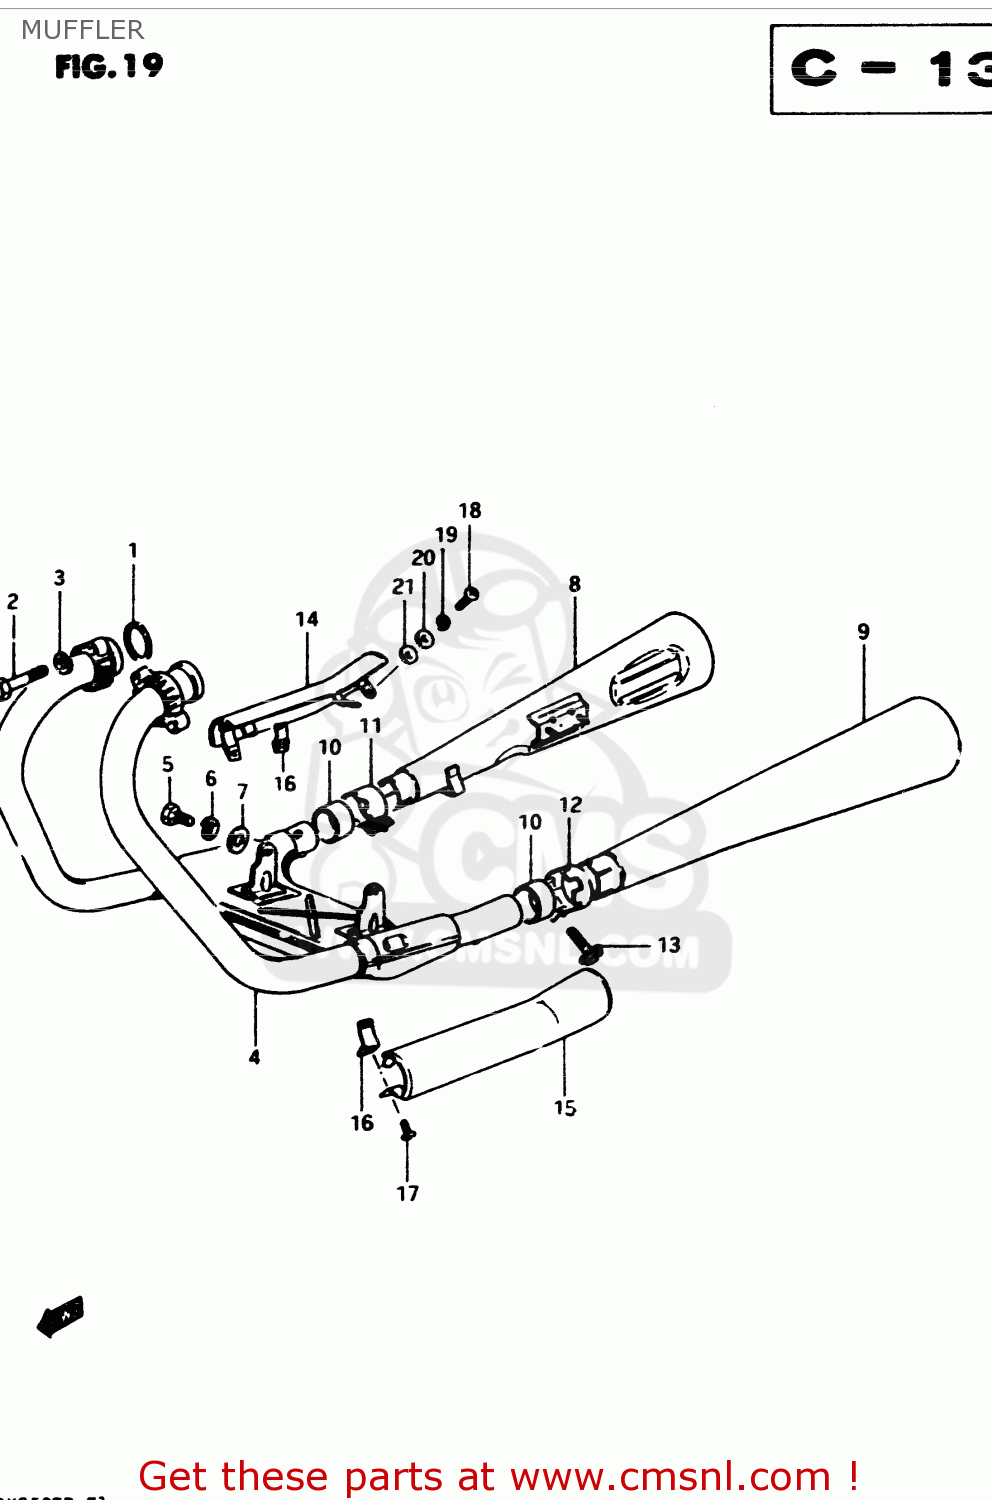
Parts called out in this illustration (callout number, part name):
1	GASKET,EXHAUST PIPE (NAS)
2	BOLT 8X40
3	LOCK WASHER
4	PIPE, EXHAUST
5	BOLT
6	LOCK WASHER
7	WASHER
8	MUFFLER, RH
9	MUFFLER ASSY,L
10	CONNECTOR,MUFFLER
11	CLAMP,MUFFLER CONNECTOR,R
12	CLAMP,MUFFLER CONNECTOR,L
13	BOLT
14	COVER,MUFFLER,RIGHT
15	COVER,MUFFLER
16	CLAMP,MUFFLER COVER
17	SCREW
18	SCREW 6X12
19	LOCK WASHER
20	WASHER
21	GASKET 6.2X12X1.5 (MCA)
